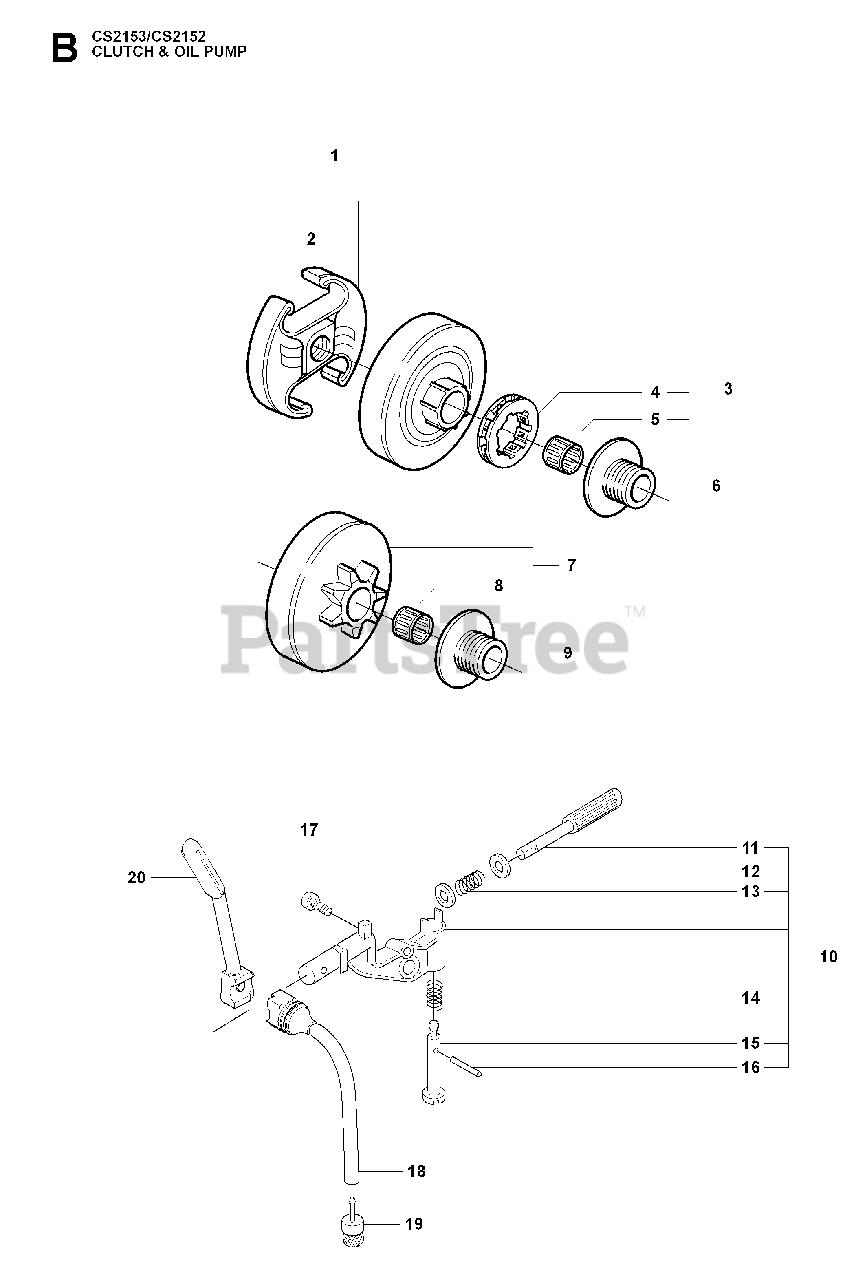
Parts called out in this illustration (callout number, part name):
2	SPRING
3	%CLUTCH DRUM
4	RIM SPROCKET 7T .325
5	NEEDLE BEARING
6	%PINION
7	CLUTCH DRUM
8	NEEDLE BEARING
10	OIL PUMP ASSY
11	PUMP PISTON
18	HOSE
19	OIL PLUMMET
20	OIL PRESSURE HOSE
